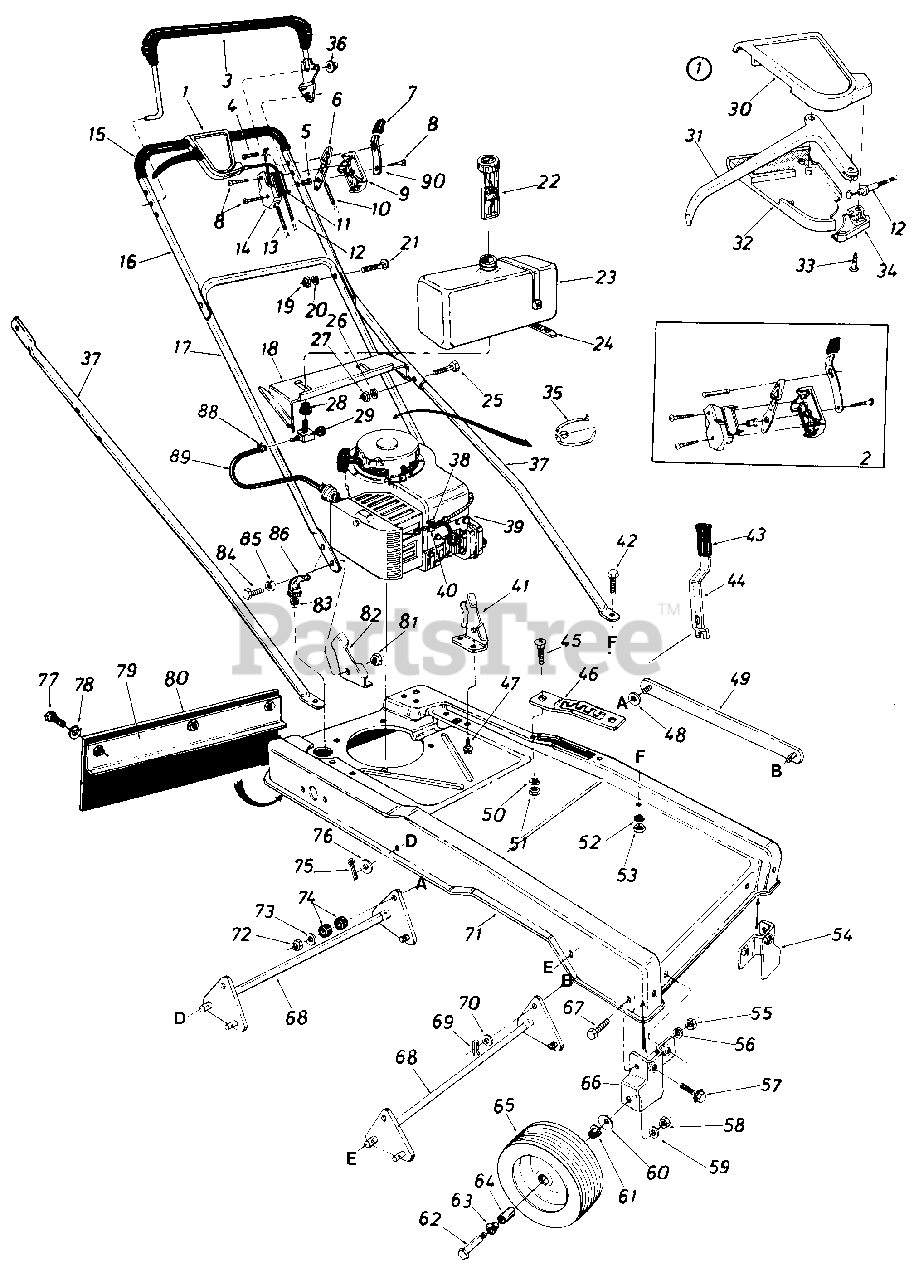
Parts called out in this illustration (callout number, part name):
1	Clutch Control Housing Comp.
2	Control Housing Comp.
3	Control Handle Ass'y.
4	Lock Pin
5	Control Disc Pin
6	Throttle Control Lever
7	Spring Lever Knob
8	Truss Mach. Hi-B Tap Scr. #12 x 1.50" Lg.
9	Control Panel Half
10	Throttle Control Wire 43" Lg. Yellow
11	Control Label Throttle
12	Self-Propelled Cable 50" Lg.
13	Drive Clutch Cable 46" Lg.
14	Clutch Panel Half
15	Grip 22" Lg.
16	Upper Handle
17	Lower Handle
18	Gas Tank Mounting Brk't.
19	Hex Nut 5/16-18 Thd.
20	L-Wash. 5/16" I.D.
21	Carriage Bolt 5/16-18 x 1.50"Lg.
22	Gas Gauge 13/4-6 x 5.50" Lg.
23	Gas Tank
24	Cable Tie 30.6" Lg.
25	Hex Bolt 5/16-24 x 1.25"Lg.
26	L-Wash. 5/16" I.D.
27	Hex Nut 5/16-24 Thd.
28	Bushing Gas Tank
29	Fuel Shut-Off Valve w/Screen
30	Control Cover Half Upper
31	Control Lever
32	Control Cover Half Lower
33	Flat "C" Sunk Hd. Tap Scr. #10 x .75" Lg.
34	Cable Mounting Cap
35	Cable Tie
36	Push Cap
37	Strut .75" O.D. x 43.44" Lg.
38	Hex Sems Scr. #10-32 x .62" Lg.
39	Engine 5 H.P.
40	Casing Clamp
41	Handle Mount Brk't. L.H.
42	Hex Bolt 5/16-18 x .75" Lg.
43	Grip Black
44	Lift Handle
45	Carriage Bolt 5/16-18 x .62"Lg.
46	Lift Handle Support Brk't.
47	Hex Wash. Hd. B-Tap Scr. 5/16-18 x .50
48	Fl-Wash. .406" I.D. x 1.25" O.D.
49	Connecting Link Ass'y.
50	L-Wash. 5/16" I.D.
51	Hex Nut 5/16-18 Thd.
52	L-Wash. 5/16" I.D.
53	Hex Nut 5/16-18 Thd.
54	Wheel Brk't. Ass'y. L.H.
55	Hex Nut 5/16-18 Thd.
56	L-Wash. 5/16" I.D.
57	Hex Sems Bolt 5/16-18 x .75" Lg.
58	Hex Cent. L-Nut 3/8-16 Thd.
59	L-Wash. 3/8" I.D.
60	Bell-Wash. .400" I.D. x .88" O.D.
61	Flanged Ball Brg. 3/8" I.D.
62	Hex Bolt 3/8-16 x 2.00" Lg.
63	Flanged Ball Brg. .501" I.D.
64	Spacer .375" I.D. x .505" O.D. x 1" Lg.
65	Wheel Ass'y. Comp. 8 x 1.75
66	Wheel Brk't. Ass'y. R.H.
67	Hex Sems Bolt 5/16-18 x .75" Lg.
68	Lift Brk't. Shaft Ass'y.
69	Intern. Cotter Pin 5/16" Dia.
70	Fl-Wash. .385" I.D. x .88" O.D.
71	Hi-Wheel Frame
72	Hex Ins. L-Nut 3/8-24 Thd.
73	Fl-Wash. .385" I.D. x .87" O.D.
74	Rubber Wash. .33" I.D. x .87" O.D.
75	Cotter Pin 1/8" Dia. x 1" Lg.
76	Fl-Wash. .510" I.D. x 1.0" O.D.
77	Hex Bolt 1/4-20 x .62" Lg.
78	L-Wash. 1/4" I.D.
79	Retaining Strip Ass'y. 2" x 15" Lg.
80	Rear Flap 7.5 x 20" Lg.
81	Hex Nut 3/8-16 Thd.
82	Handle Mount Brk't.
83	Part of Engine
84	Hex Bolt 3/8-16 x .75" Lg.
85	L-Wash. 3/8" I.D.
86	90 Deg. Elbow Male to Female 3/8
88	Hose Clamp .406" Dia.
89	Fuel Line 15" Lg.
90	Lockout Lever
